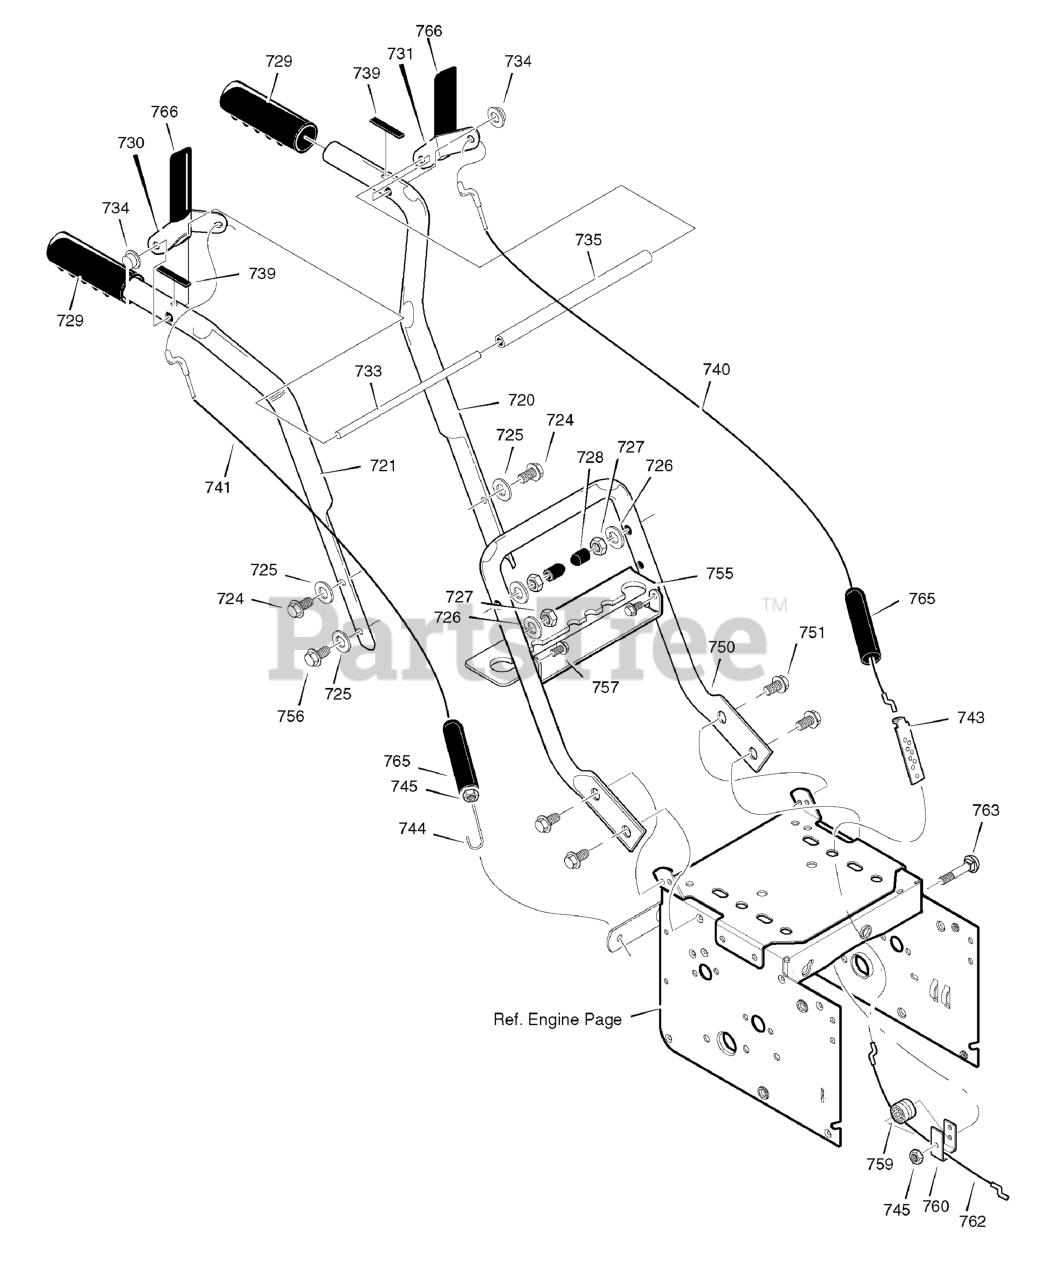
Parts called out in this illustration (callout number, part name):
720	HANDLE, Upper L.H.
721	HANDLE, Upper R.H.
724	SCREW, 5/16-18 x 2-3/4
725	WASHER, Flat
726	WASHER, Split Lock
727	NUT, Hex, 5/16 - 18
728	STOP, Red Plastic
729	GRIP, Finger Handle
730	LEVER ASSEMBLY, Clutch Drive R.H.
731	LEVER ASSEMBLY, Clutch Drive L.H.
733	ROD, Pivot Clutch
734	NUT, Push-Pal
735	SPACER, Handle
739	BUMPER, Rectangular
740	CABLE, Clutch, 28.44
741	CABLE, Auger Clutch
743	BRACKET, Cable Adjuster
744	SPRING, Auger Clutch
745	NUT, 1/4 - 20
750	HANDLE, Lower
751	SCREW
755	BRACKET, Gear Selector
756	SCREW, 5/16-18 x 2
757	SCREW, 1/4 - 20 x 5/8
759	CABLE SPOOL, Auger Clutch
760	BRACKET, Cable Spool
762	CABLE, Lower Drive, 12
763	BOLT, Hex, 1/4 - 20 x 1-1/2
765	BOOT, Clutch Spring
766	GRIP
